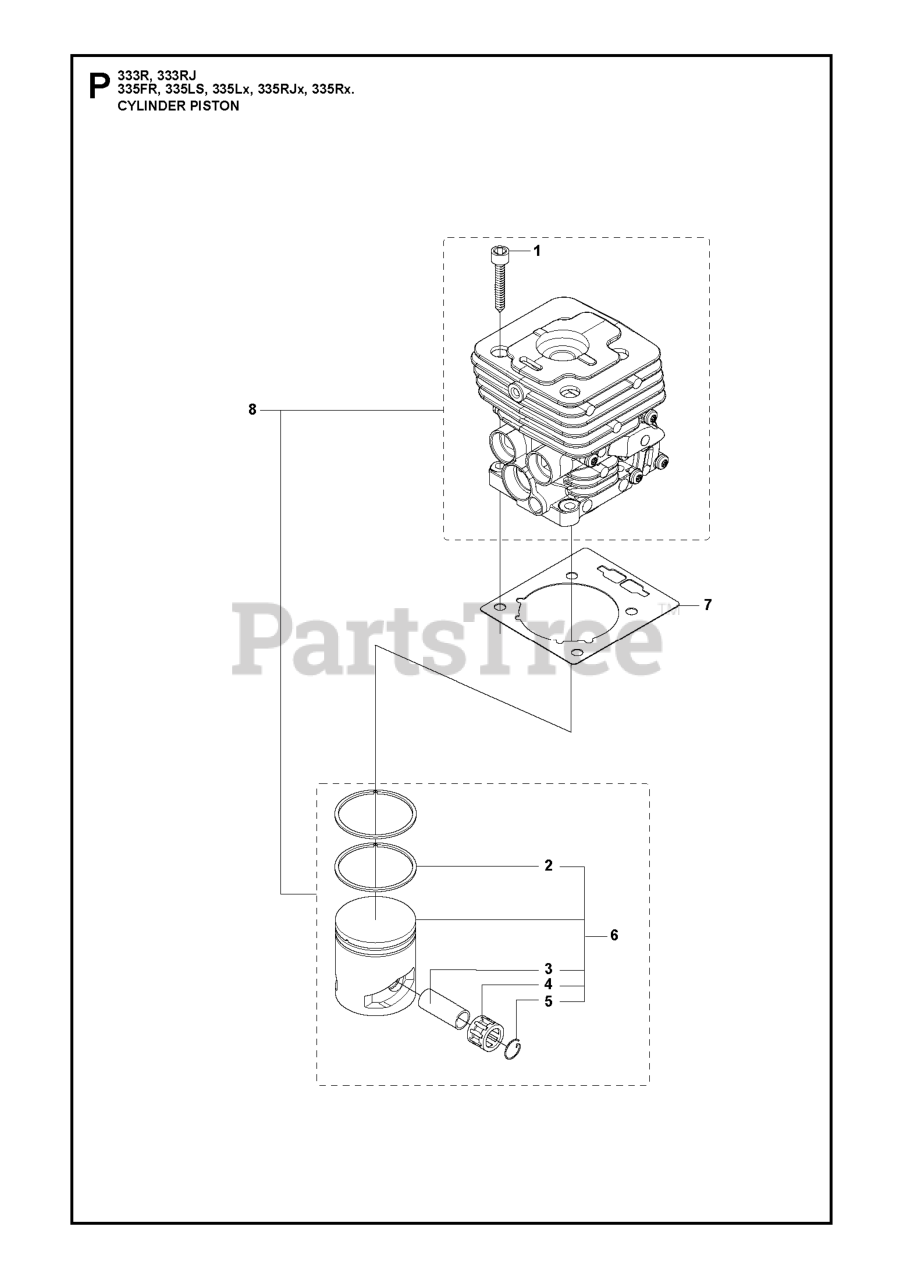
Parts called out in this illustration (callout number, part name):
1	SCREW
2	PISTON RING
3	PISTON BOLT
4	SUPPORT BUSHING
5	LOCKING RING
6	RP PISTON CPL
7	GASKET CYLINDER
8	%CYLINDER CPL
